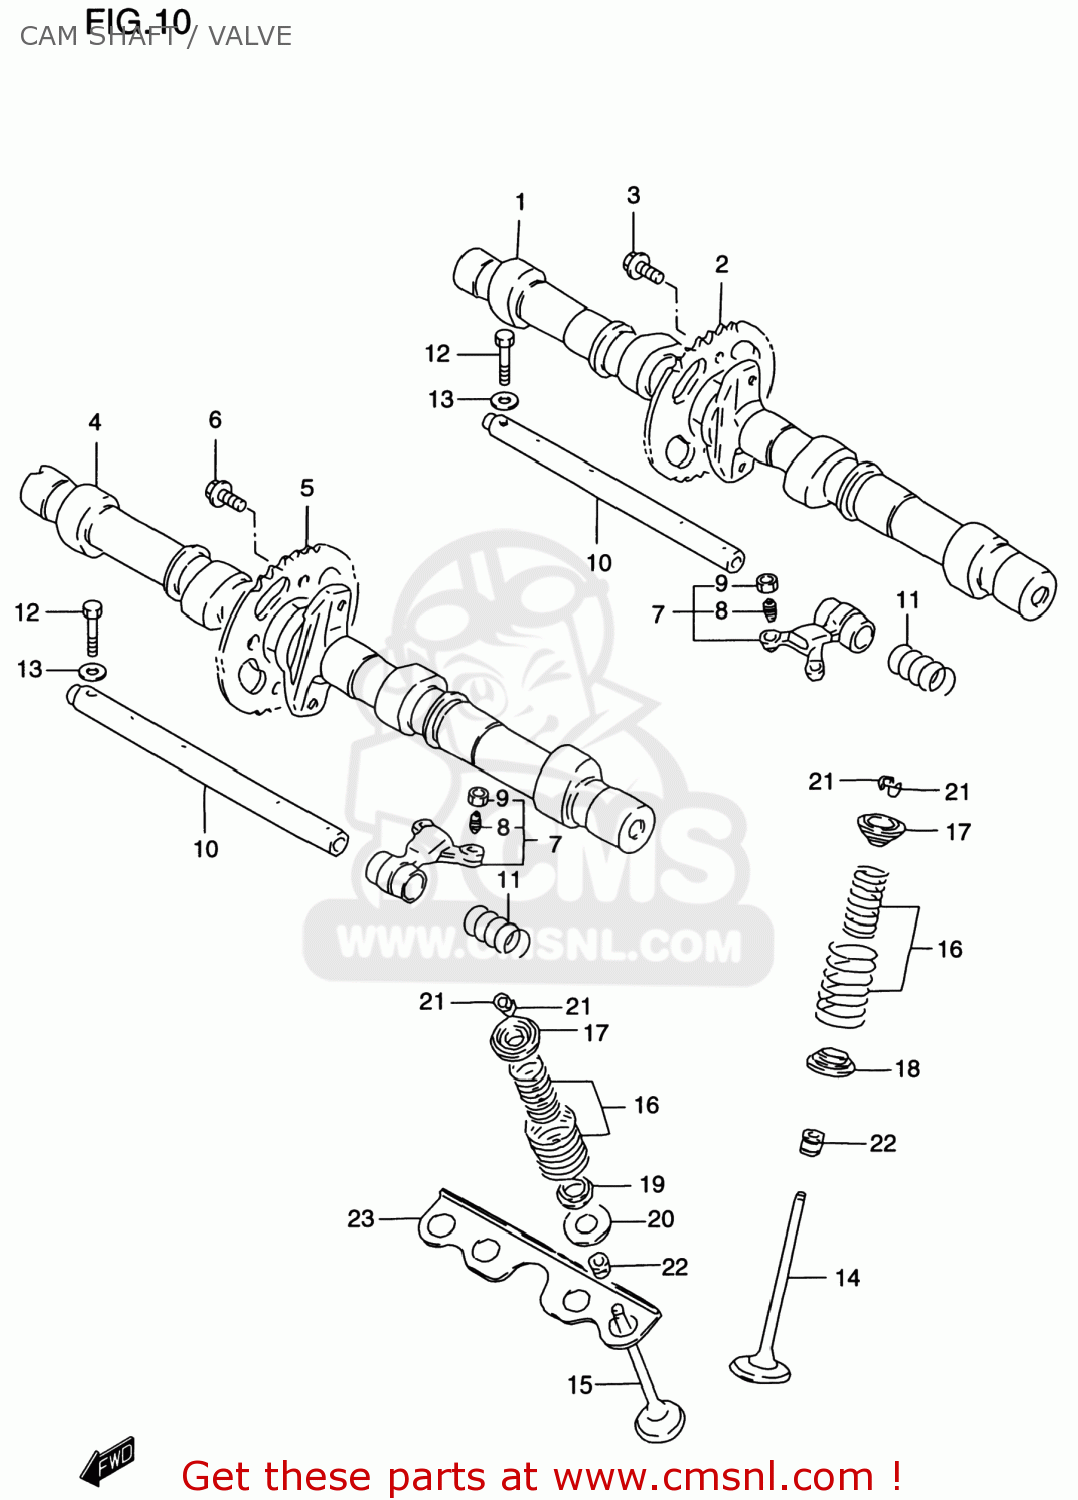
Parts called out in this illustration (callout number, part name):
1	CAMSHAFT,INTAKE
2	SPROCKET,CAMSHAFT
3	BOLT(7X11)
4	CAMSHAFT,EXHAUST
5	SPROCKET,CAMSHAFT
6	BOLT(7X11)
7	ARM,VALVE ROCKER
8	SCREW,TAPPET ADJUSTING
9	NUT,TAPPET ADJUSTING
10	SHAFT,VALVE ROCKER ARM
11	SPRING
12	BOLT
13	WASHER
14	VALVE,INTAKE
15	VALVE,EXHAUST
16	SPRING SET,VALVE
17	RETAINER,VALVE SPRING
18	SEAT,VALVE SPRING
19	SEAT,VALVE SPRING EXH INNER
20	SEAT,VALVE SPRING EXH OUTER
21	COTTER VALVE
22	SEAL,OIL(5X10X9.7)
23	PLATE,VALVE SEAT
